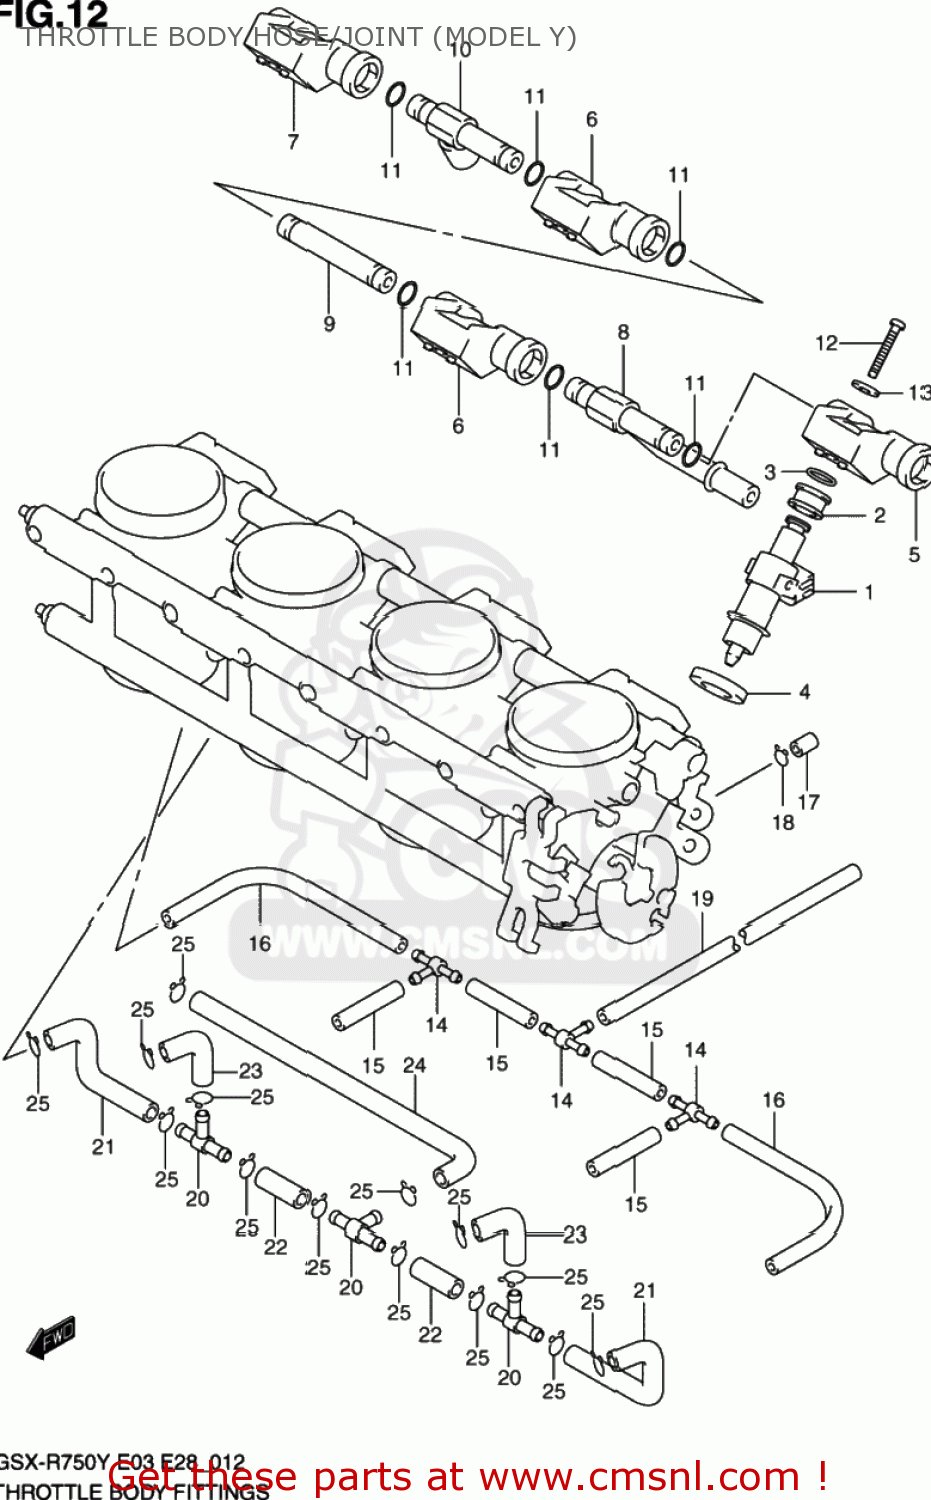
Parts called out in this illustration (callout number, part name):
1	INJECTOR ASSY
2	RING,CUSHION
3	O RING
4	RING,SEAL
5	JOINT NO.1
6	JOINT NO.2,3
7	JOINT NO.4
8	JOINT
9	JOINT
10	JOINT
11	O RING
12	SCREW
13	WASHER
14	JOINT
15	HOSE,RUBBER(L:35)
16	HOSE,RUBBER(L:100)
17	CAP,RUBBER
18	CLIP
19	HOSE,RUBBER(3X7X170)
20	JOINT
21	HOSE,RUBBER(L:80+25)
22	HOSE,RUBBER(L:35)
23	HOSE,RUBBER(L:30+30)
24	HOSE,RUBBER(L:200+30)
25	CLIP
